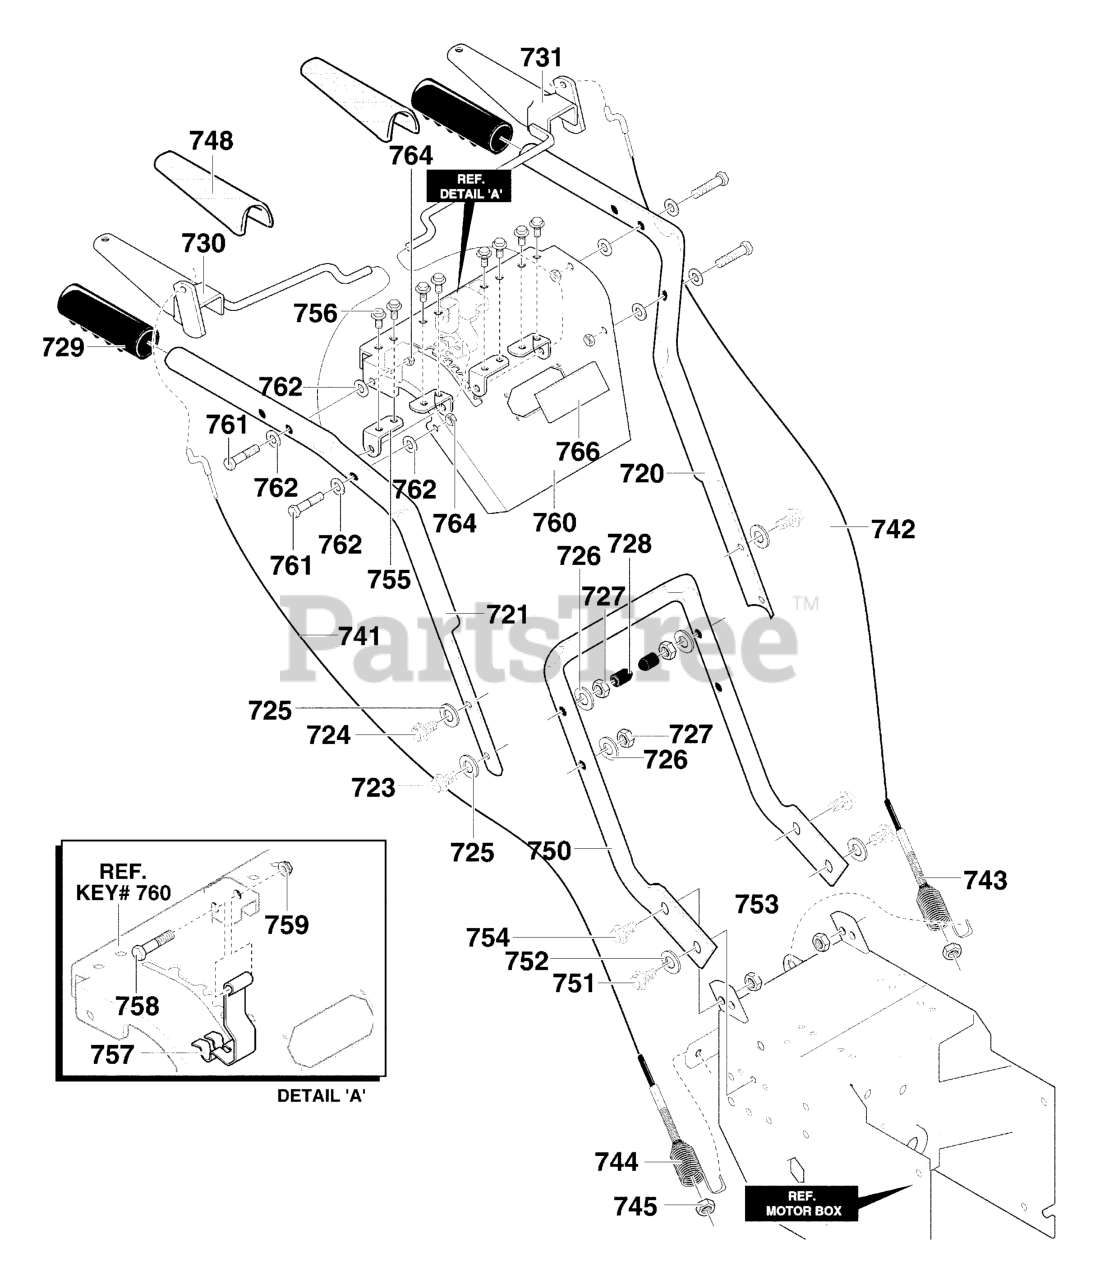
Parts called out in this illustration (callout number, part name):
720	HANDLE, UPPER LH
721	HANDLE, UPPER RH
723	SCREW, 3/8-16 x 2.00
724	SCREW, 3/8-16 x 3.00
725	WASHER, FLAT
726	WASHER, .38ID
727	NUT, 3/8-16 REGHXCTRLK
728	STOP, PLASTIC
729	GRIP, HANDLE
730	ASSY, CLUTCH LEVER RH
731	ASSY, CLUTCH LEVER LH
741	CABLE, CLUTCH 27.50"
742	CABLE, CLUTCH 32.19"
743	SPRING, TENSION
744	SPRING, AUGER CLUTCH
745	NUT, 1/4-20 HEX NYLOCK
748	GRIP, CLUTCH HANDLE
750	HANDLE, LOWER
751	SCREW, 5/16-18 x 0.75
752	WASHER, .31X.58X.08
753	NUT, 5/16-18RGHXCTRLK
754	SCREW, 5/16-18 x 0.75
755	BRACKET, ROD GUIDE
756	SCREW 1/4-20X.38
757	SPRING, CAM LOCK
758	BOLT, HHSH 5/16-18
759	NUT, 5/16-18 HEXNYL
760	ASSY, PANEL
761	SCREW 5/16-18X1.75
762	FLATWASHER
764	NUT 5/16-18 HEXWDFLLK
766	PLATE, PANEL
